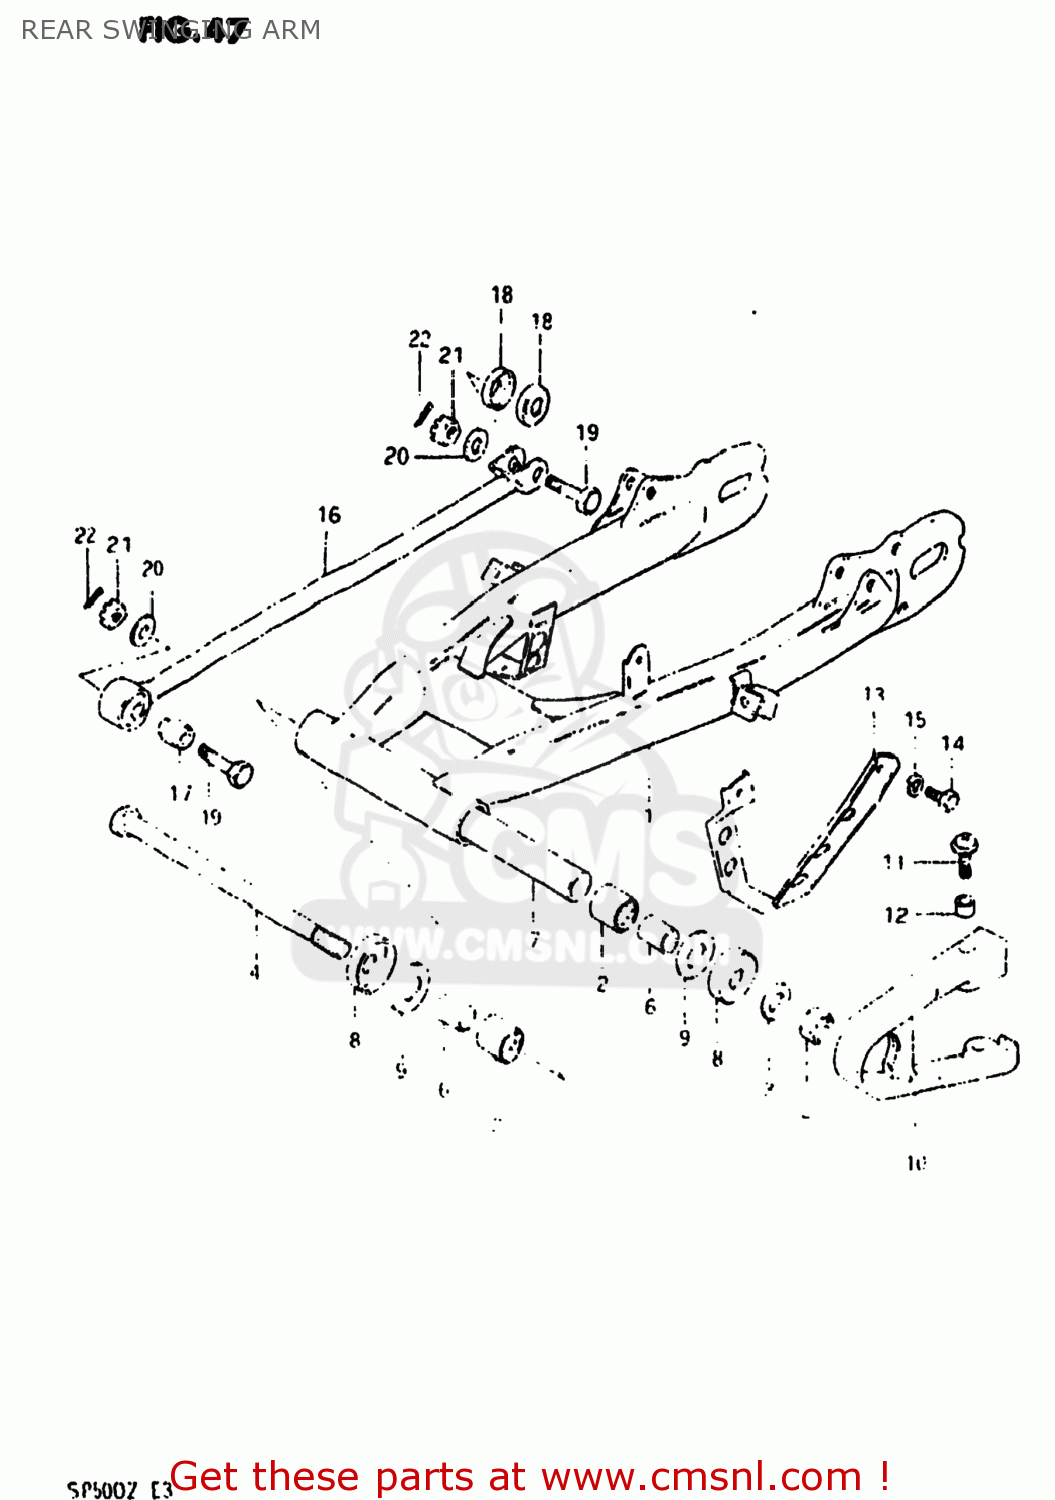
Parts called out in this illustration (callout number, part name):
1	ARM,REAR SWING
2	BEARING(22X29X20)
3	WASHER
4	SHAFT,REAR SWING ARM
5	NUT 16MM
6	SPACER,RR SWGARM PIVOT
7	SPACER (16.2X21.7X142)
8	COVER,RR SWGARM DUST SEAL
9	WASHER
10	BUFFER,CHAIN TOUCH DEFLECTOR
11	SCREW,CHAIN TOUCH DEFEND
12	SPACER (5.5X8X4)
13	GUIDE,CHAIN
14	BOLT 8X12
15	LOCK WASHER
16	TORQUE LINK,REAR
17	BUSH
18	19-1
19	BOLT 8X28
20	WASHER
21	NUT 8MM
22	PIN 20X20
